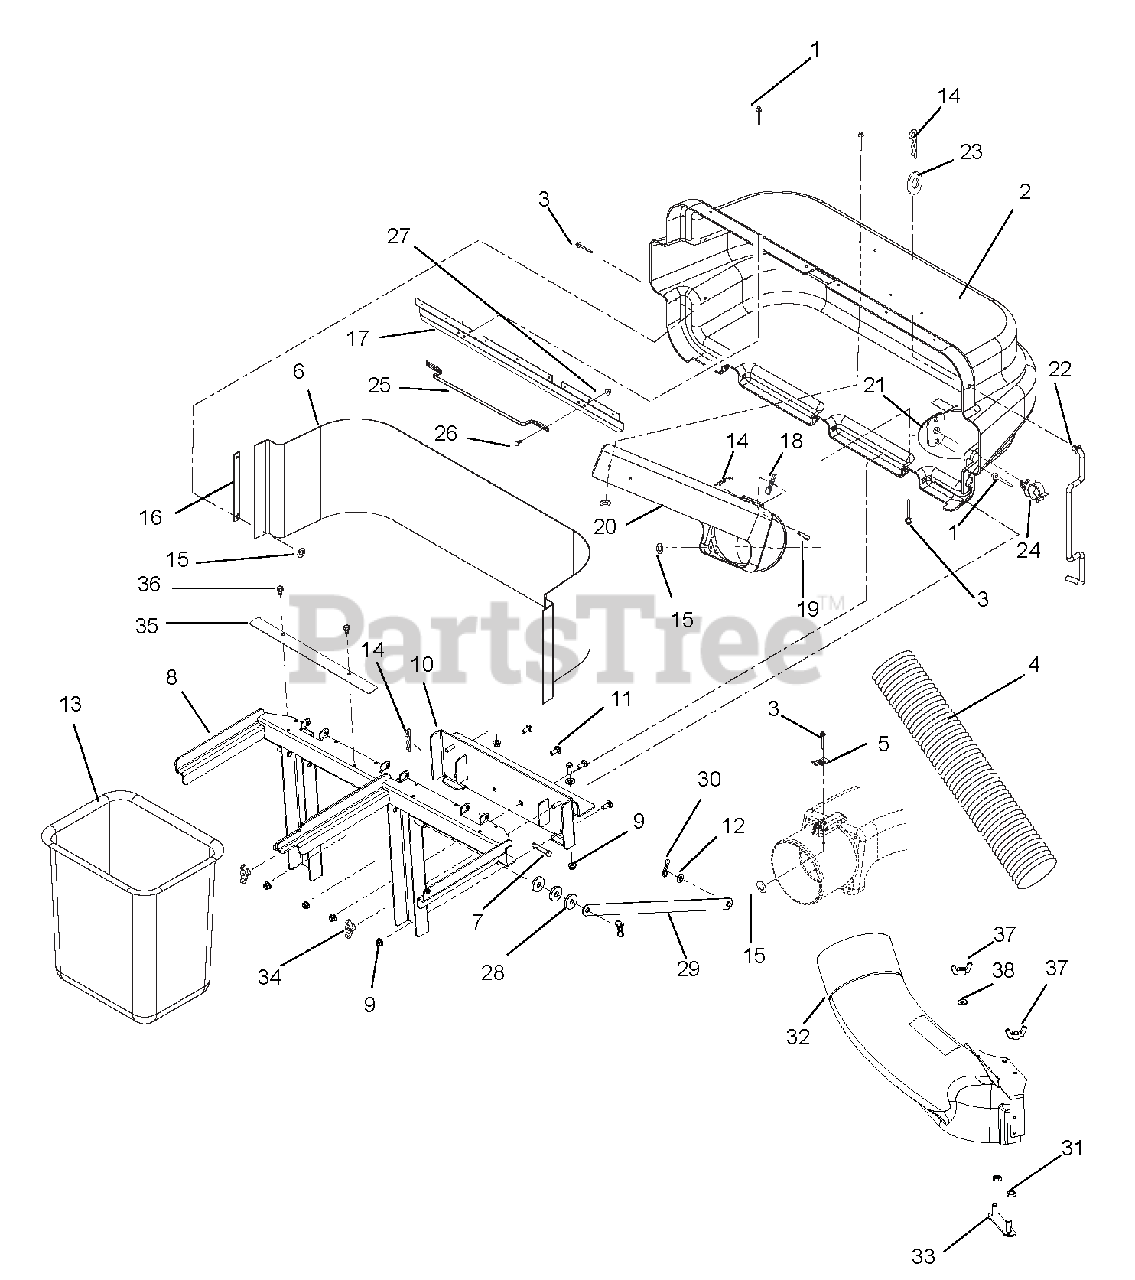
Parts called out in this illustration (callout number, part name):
1	RVT-POP .187X.402 DOME ST
2	BAGGER COVER W/DECAL
3	RVT-POP .187X.375
4	HOSE, FLEXIBLE-47"
5	THUMB LATCH
6	SCREEN, BAGGER
7	PIN-CLEV .371X3.25 YWZC
8	WMT, BAGGER FRAME
9	@NUT-LK-NYL-FLG .38-16 YWZC
10	WMT, MOUNTING PLATE
11	@BLT-RDHDSQNK .38-16X1.00 G5YZ
12	@WSHR-FL-STL.438X1.00X.083 YWZ
13	BAG, MESH ZOOM
14	PIN-HAIR, ENDRIES #25 YWZC
15	@WSHR-FL-STL.219X.50X.049 YWZC
16	STRAP,COVER
17	LATCH, BAGGER (MZ)
18	INDICATOR, FLOW
19	PIN-CLEV .309 X 1.625 YWZC
20	BOOT,UPPER
21	PLATE, ROD CLIP
22	PROP-ROD,BAGGER
23	@WSHR-FL-STL.406X.812X.065 YWZ
24	CLIP-.38
25	BAGGER HANDLE
26	@BLT-RDHDSQNK .25-20X.75 G5YZ
27	NUT-LUG .50-20 YWZC
28	WSHR-FL-STL .515X1.625X.250 YZ
29	PIN,BOW TIE LOCKING .091X1.875
30	WMT-STRAP, BAGGER
31	@NUT-LK-CTR-JAM .31-18 YWZC
32	ASM, BAGGER BOOT
33	WMT-BOOT MOUNT STRAP
34	NUT-WING .38-16
35	BRKT-BAGGER OVERLAP
36	@SCR-TAP .31-18X.50 HWH TR YWZ
37	NUT-NYLK WING .312-18 YWZC
38	@WSHR-FL-STL.406X.812X.065 YWZ
